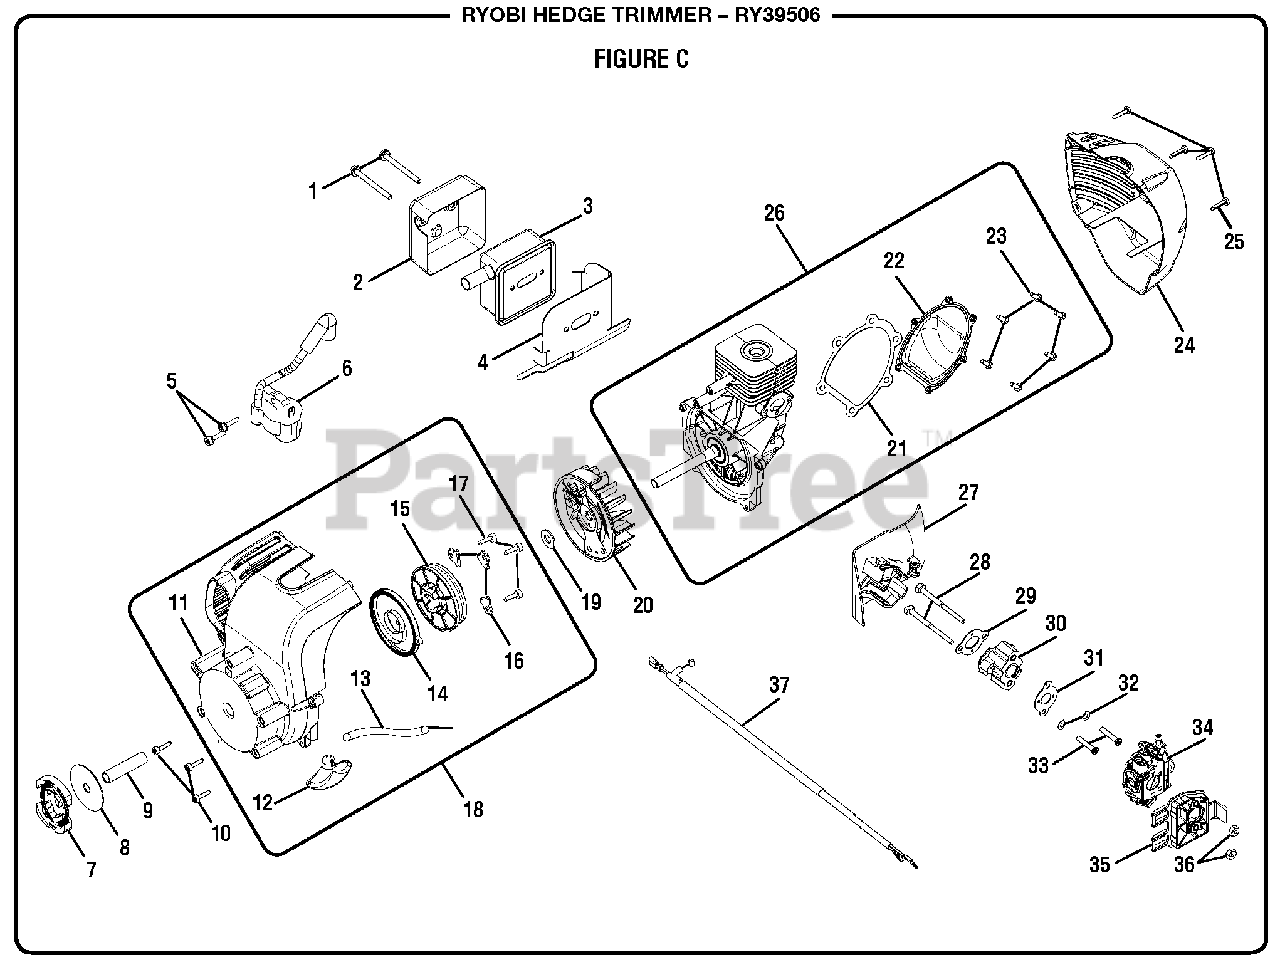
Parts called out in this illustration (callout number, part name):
1	Screw (12-24 x 52 mm)
2	Heat Shield (Muffler)
3	Muffler Assembly
4	Muffler Gasket
5	Screw (M4 x 19 mm)
6	Ignition Module
7	Clutch Assembly
9	Spacer Tube
10	Screw (M4 x 16 mm)
11	Lower Housing w/Label
12	Starter Grip
13	Starter Rope
14	Spring & Container Assembly
15	Starter Pulley
16	Pulley Retainer
17	Screw (M4 x 14 mm)
18	Lower Housing Start Assembly
19	Washer
20	Flywheel Assembly
21	Crankcase Cover Gasket
22	Crankcase Cover
23	Screw (M4 x 12 mm)
24	Upper Housing
25	Screw (M4 x 18 mm)
26	Short Block Assembly
27	Baffle Plate
28	Screw (M5 x 62 mm)
29	Intake Gasket
31	Heat Dam Gasket
33	Screw (M5 x 25 mm)
34	Carburetor
35	Air Box Base
36	Lock Nut (M5)
37	Throttle Cable And Lead Wire Assembly
